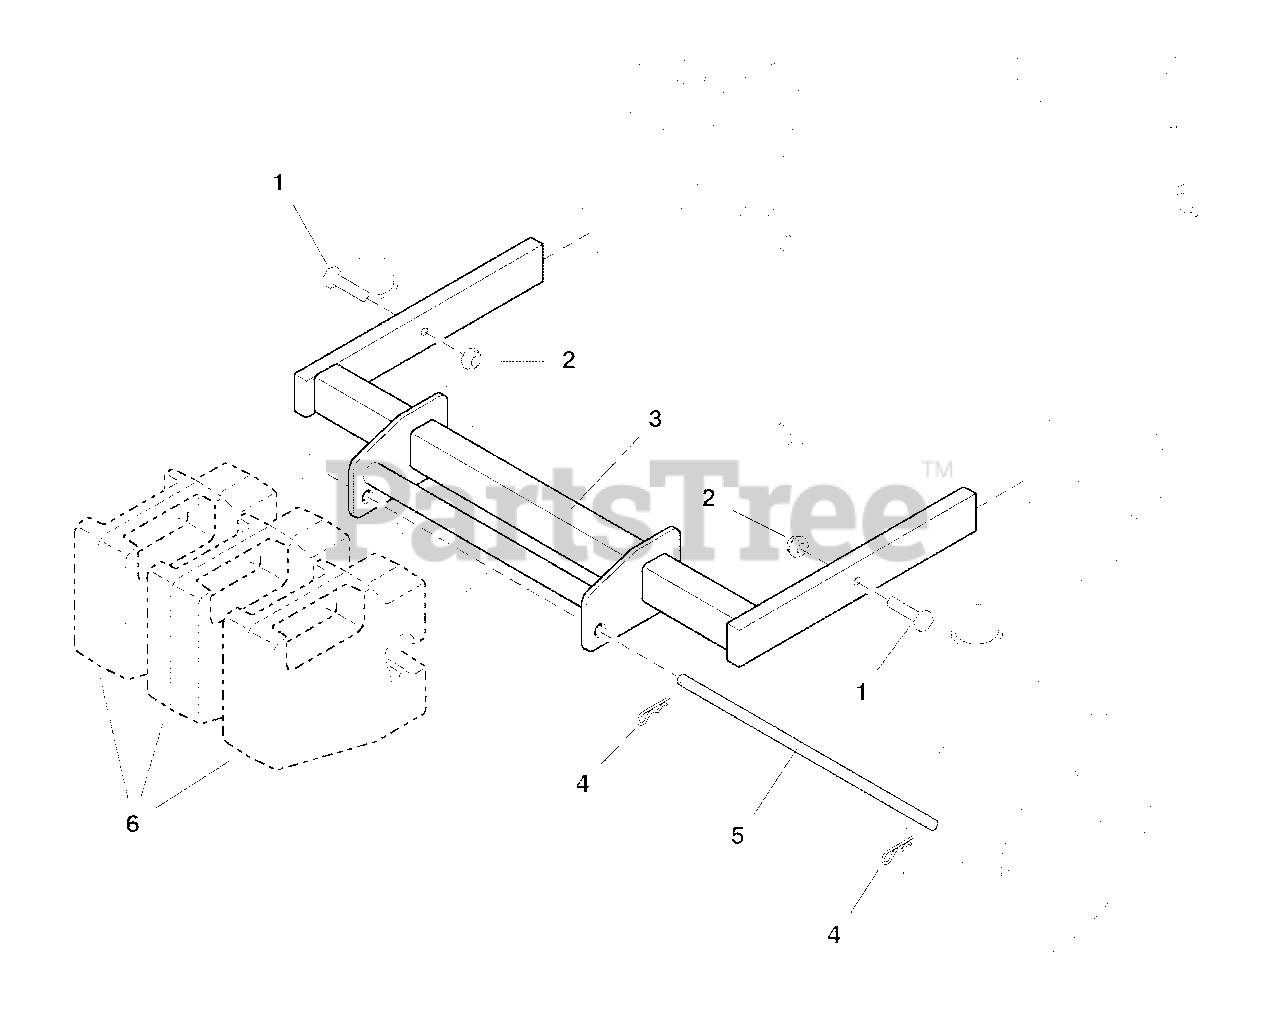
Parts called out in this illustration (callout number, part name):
1	BOLT, 3/8-16 X 2" GD5 YZ
2	NUT, 3/8-16 HEX NYLON LOCK
3	3-BAG WEIGHT RACK WELDMENT
4	PIN, HAIR, .0915 X 1-7/8
5	ROD, WEIGHT RETAINER
6	WEIGHT, 50 lbs.
